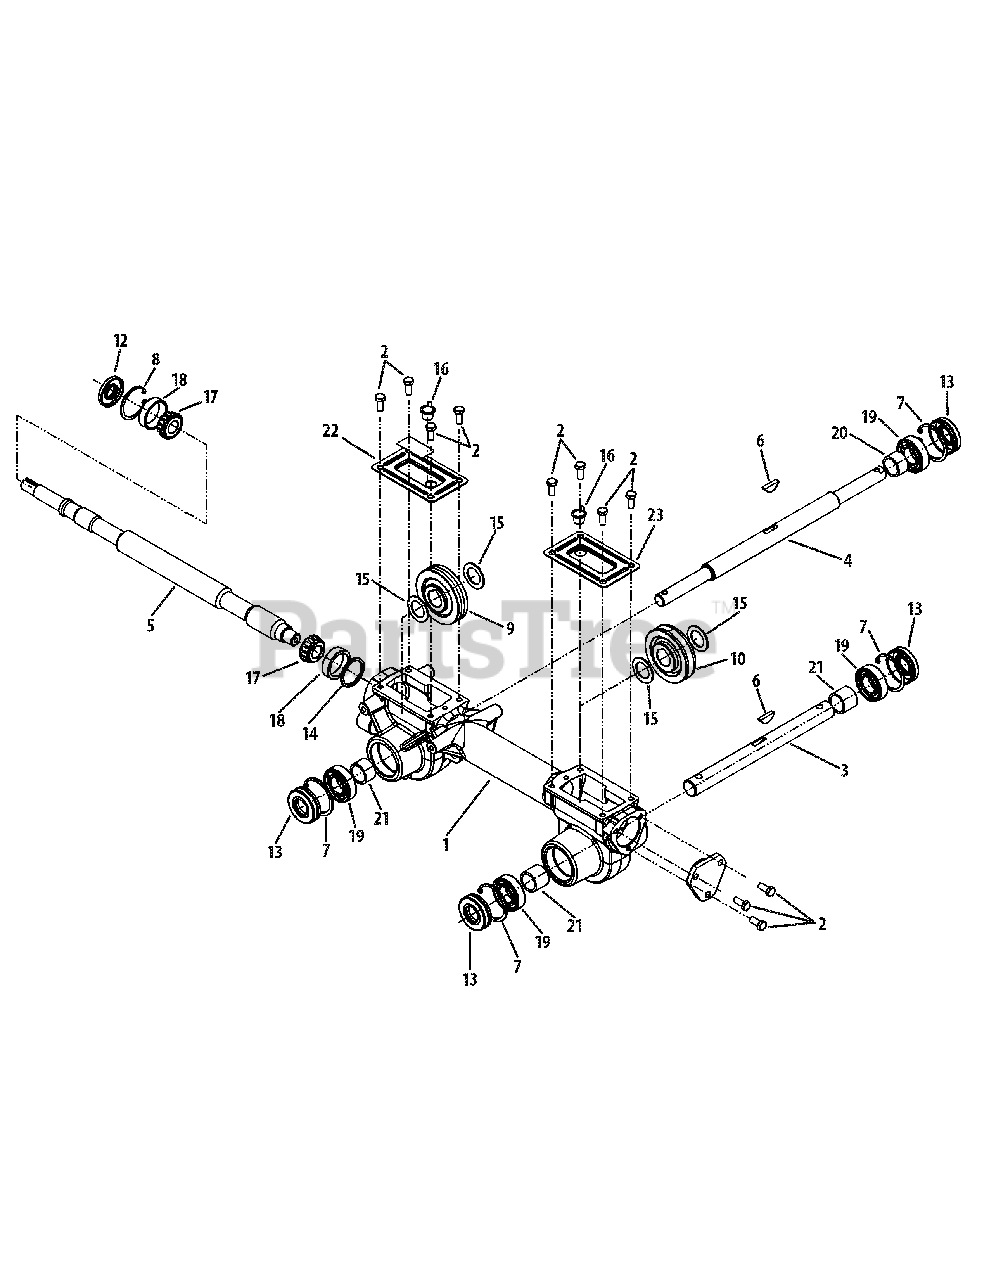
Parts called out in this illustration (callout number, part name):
1	Transmission Housing
2	Hex Screw, 5/16-18 x .75
3	Shaft
4	Wheel Shaft
5	Drive Shaft
6	Hi-Pro Key, .25 x 1.062
7	Retaining Ring
8	Retaining Ring
9	Worm Gear, 61T
10	Worm Gear, 30T
11	Bearing Cover
12	Oil Seal, .750 x 1.783
13	Oil Seal, 1.00 x 2.00
14	Flat Washer, 1.50 x 1.75 x .062
14	Flat Washer, 1.50 x 1.75 x .005
14	Flat Washer, 1.50 x 1.75 x .03
14	Flat Washer, 1.50 x 1.75 x .010
15	Flat Washer, 1.010 x 1.56 x .060
16	Plastic Plug
17	Cone Bearing
18	Cup Bearing
19	Ball Bearing
20	Spacer, 1.00 x 1.25 x .73
21	Spacer, 1.00 x 1.25 x .98
22	Transmission Cover
23	Transmission Cover Front
